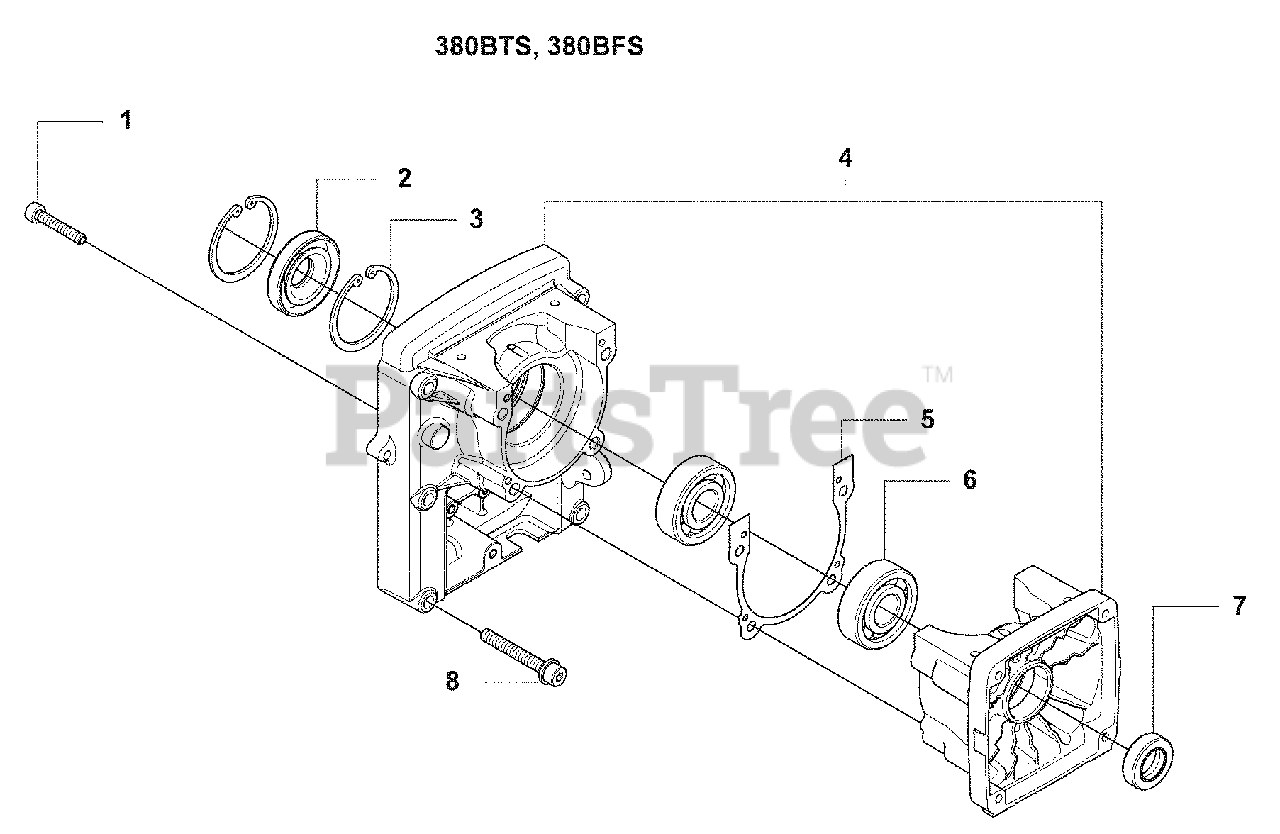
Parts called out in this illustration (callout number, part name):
1	Bolt
2	Seal
3	Snap Ring
4	CRANKCASE-C
5	Gasket
6	Ball Bearing
7	Seal
